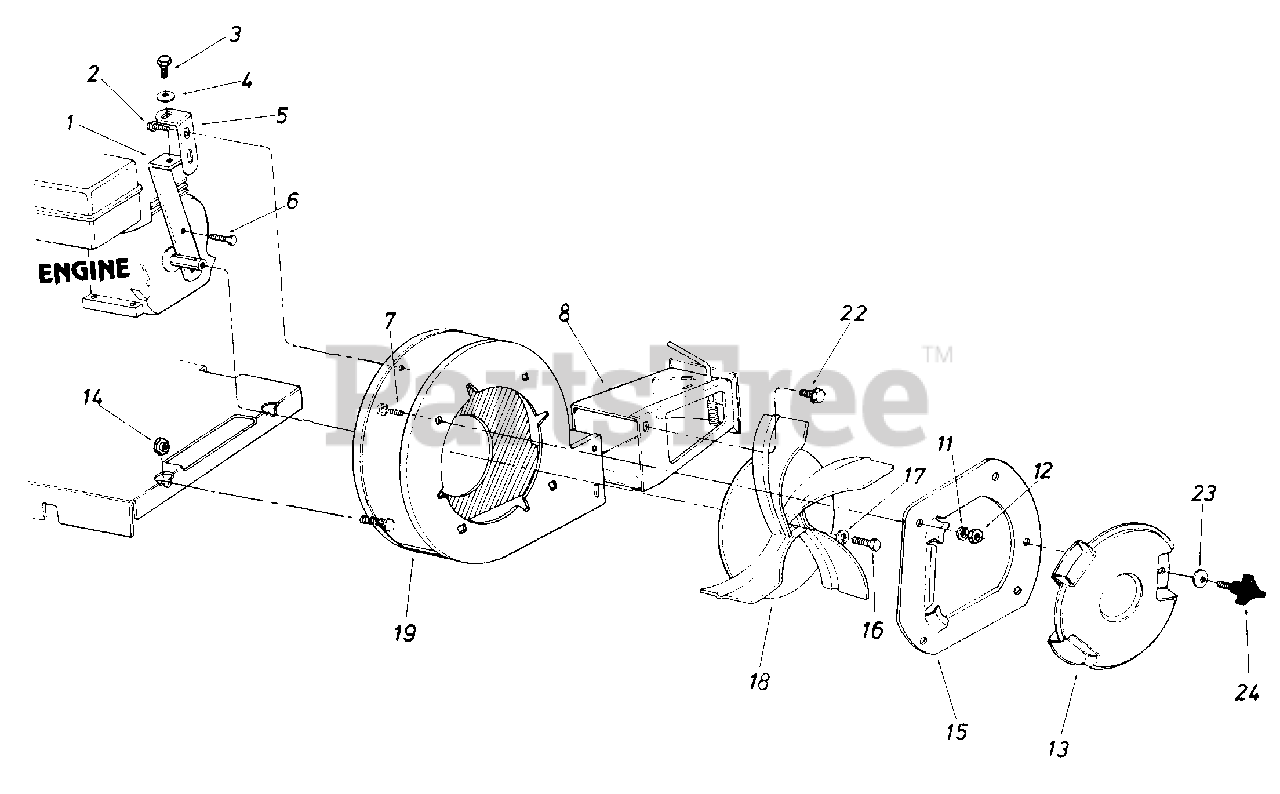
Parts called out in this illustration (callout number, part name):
3	Hex Bolt 5/16-18 x .75" Lg.
4	L.-Wash. 5/16" I.D.
7	Carriage Bolt 5/16-18 x .62" Lg.
12	Hex Nut 5/16-18 Thd.
13	Blower Guard
14	Hex Shoulder Nut.50" I.D.
15	Nozzle Plate Ass'y.
16	Hex Bolt 3/8-24 x 1.25" Lg.
17	L.-Wash. 3/8" I.D. HD.
18	Air Vane Plate Ass'y.
19	Blower Housing Ass'y. - Comp.
22	Hex Sems Bolt 5/16-18 x .62" Lg.
23	Bellevi1e Wash. 34 " 1. D. x .87 " 0. D.
24	3-Arm Thumb Scr. 5/16-18 x .75" Lg.
